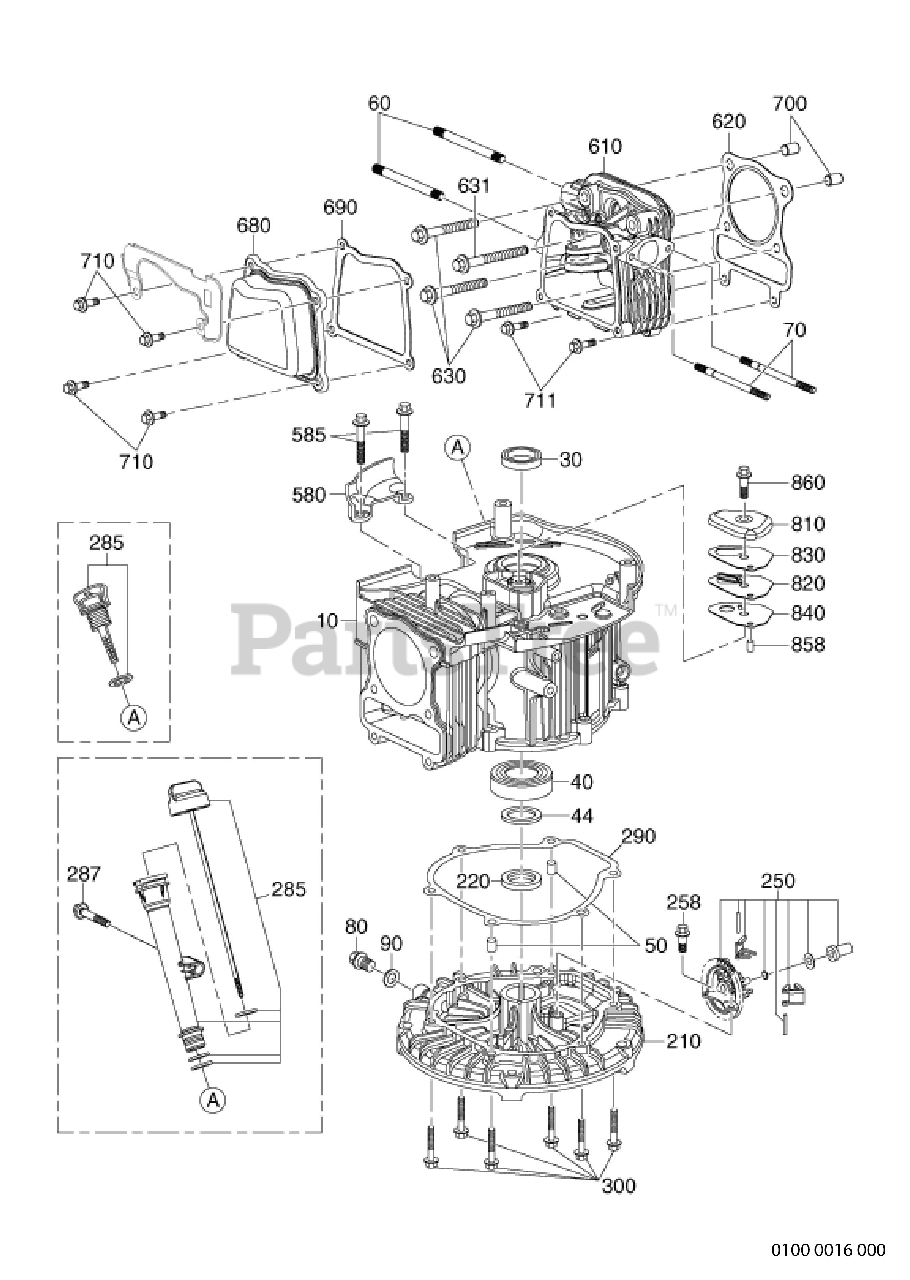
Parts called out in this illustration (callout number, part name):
10	CRANKCASE ASSY
30	OIL SEAL
44	WASHER
50	DOWEL PIN
60	STUD
70	STUD
90	WASHER
210	CRANKCASE COVER
220	OIL SEAL
250	GOVERNOR GEAR ASSY
258	BOLT
287	BOLT
300	BOLT
585	BOLT
610	CYLINDER HEAD ASSY
620	CYLINDER HEAD GASKET
630	BOLT
631	BOLT
690	VALVE COVER GASKET
700	DOWEL PIN
710	BOLT
711	BOLT
830	BREATHER COV GASKET
840	BREATHER COV GASKET
860	BOLT
